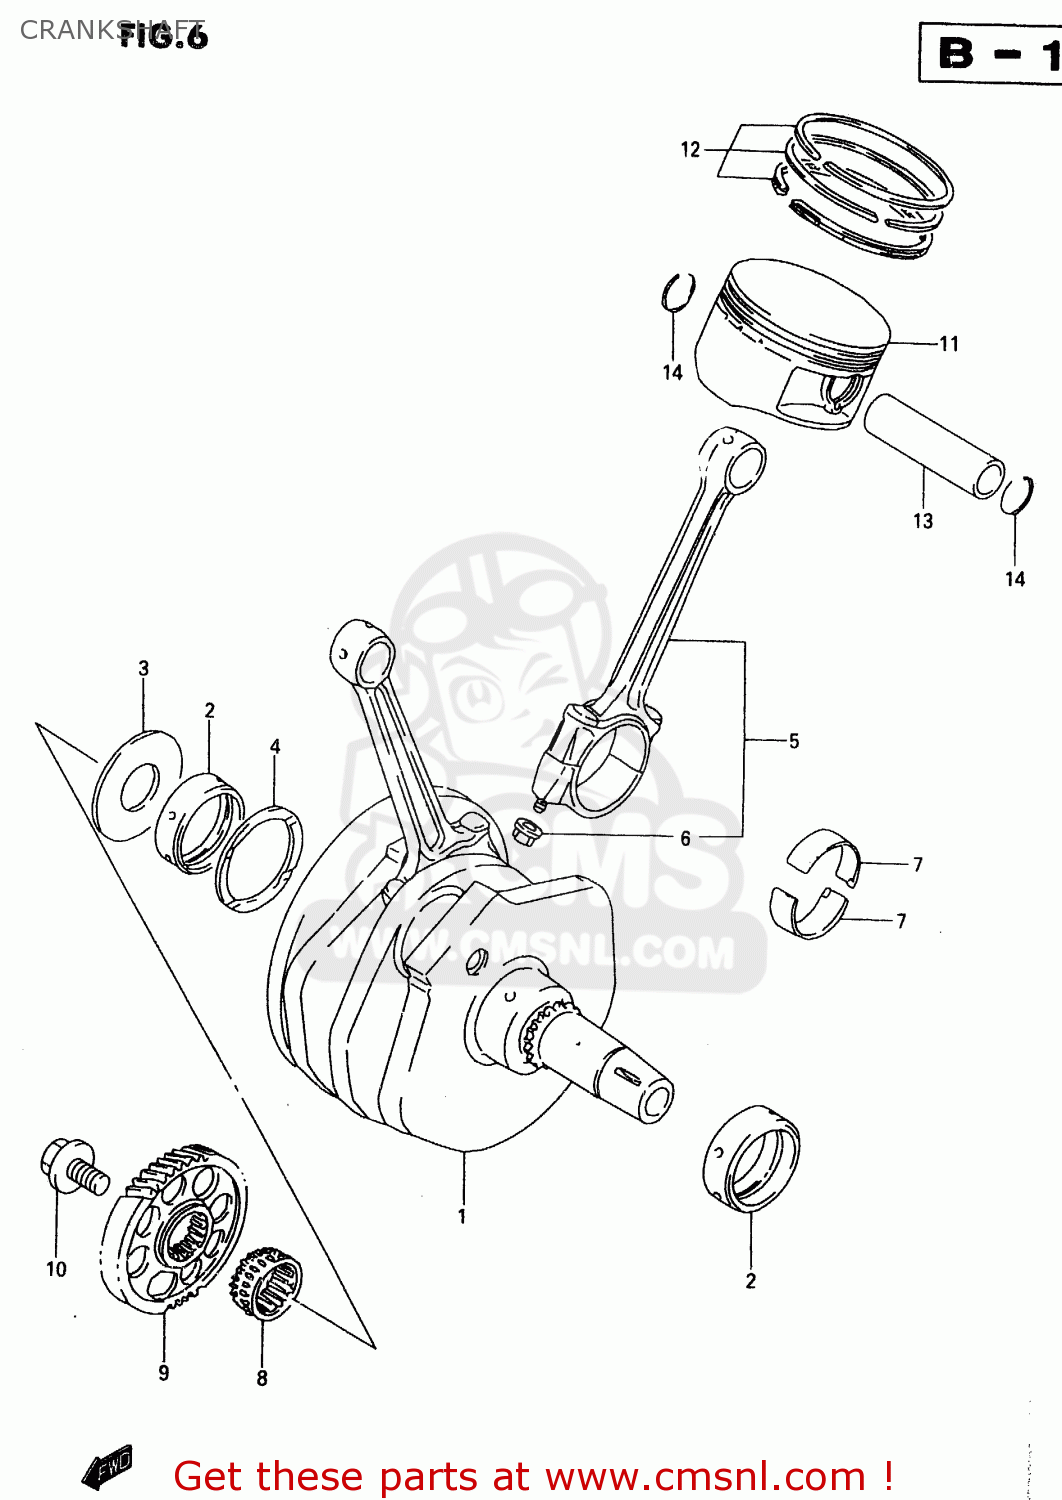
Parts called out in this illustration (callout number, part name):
1	CRANKSHAFT SET
2	METAL,CRANKSHAFT
3	WASHER,CRANK THRUST
4	PLATE,CRANK THRUST
5	CONNECTING ROD ASSY
6	NUT
7	METAL,CRANK PIN
8	SPROCKET,CAM CHAIN DRIVE,R
9	GEAR,PRIMARY DRIVE
10	BOLT(14X28)
11	PISTON
12	RING SET,PISTON
13	PIN,PISTON
14	CIRCLIP
